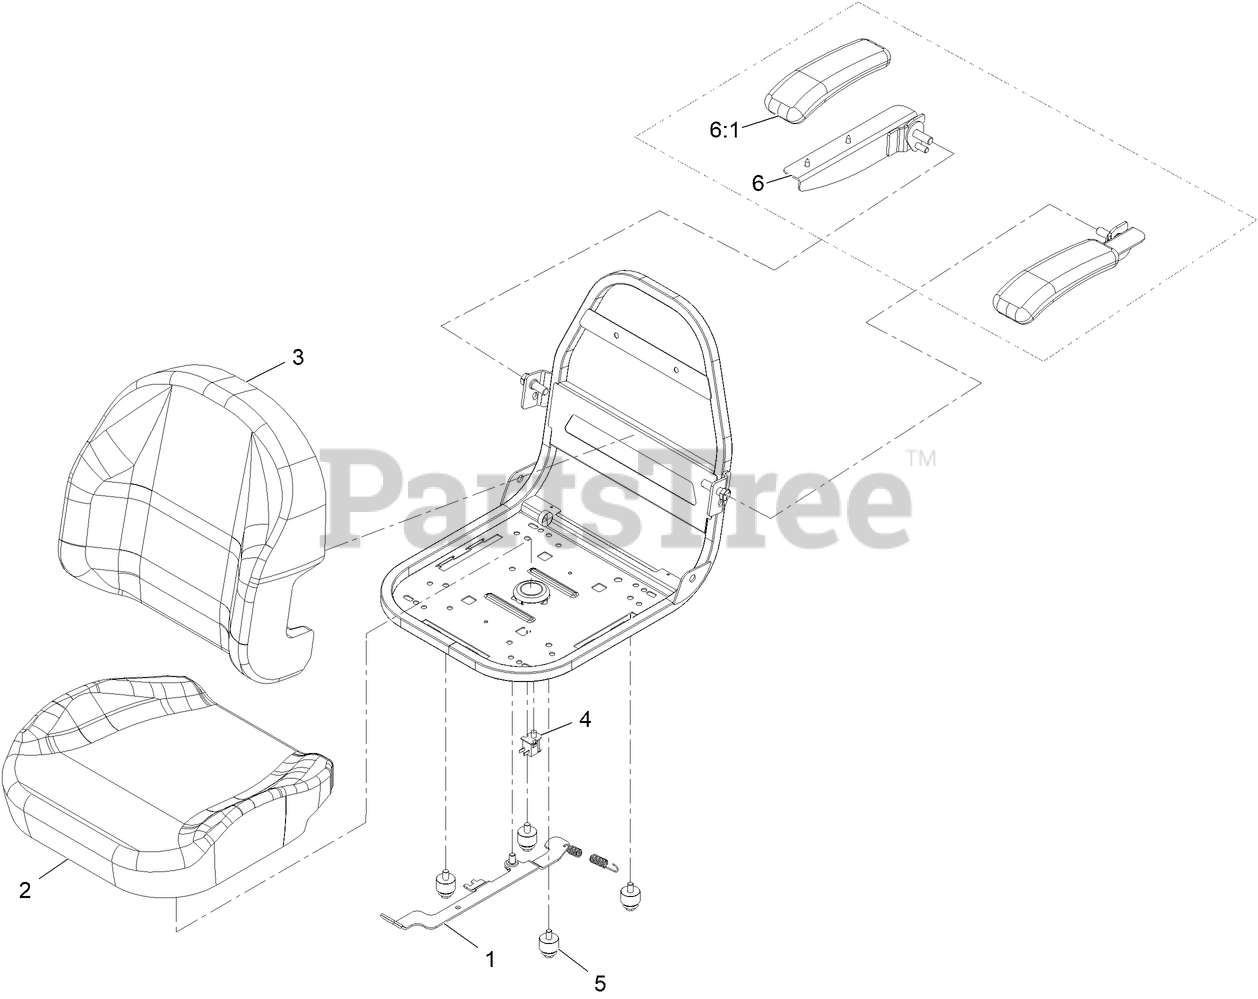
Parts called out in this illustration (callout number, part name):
1	TRACK ASM
2	Cushion-Seat Bottom
3	Cushion-Seat Back Exmark
4	SWITCH-BAIL
5	BUSHING ASM
6	ARMREST KIT
6:1	CUSHION-REST, ARM
